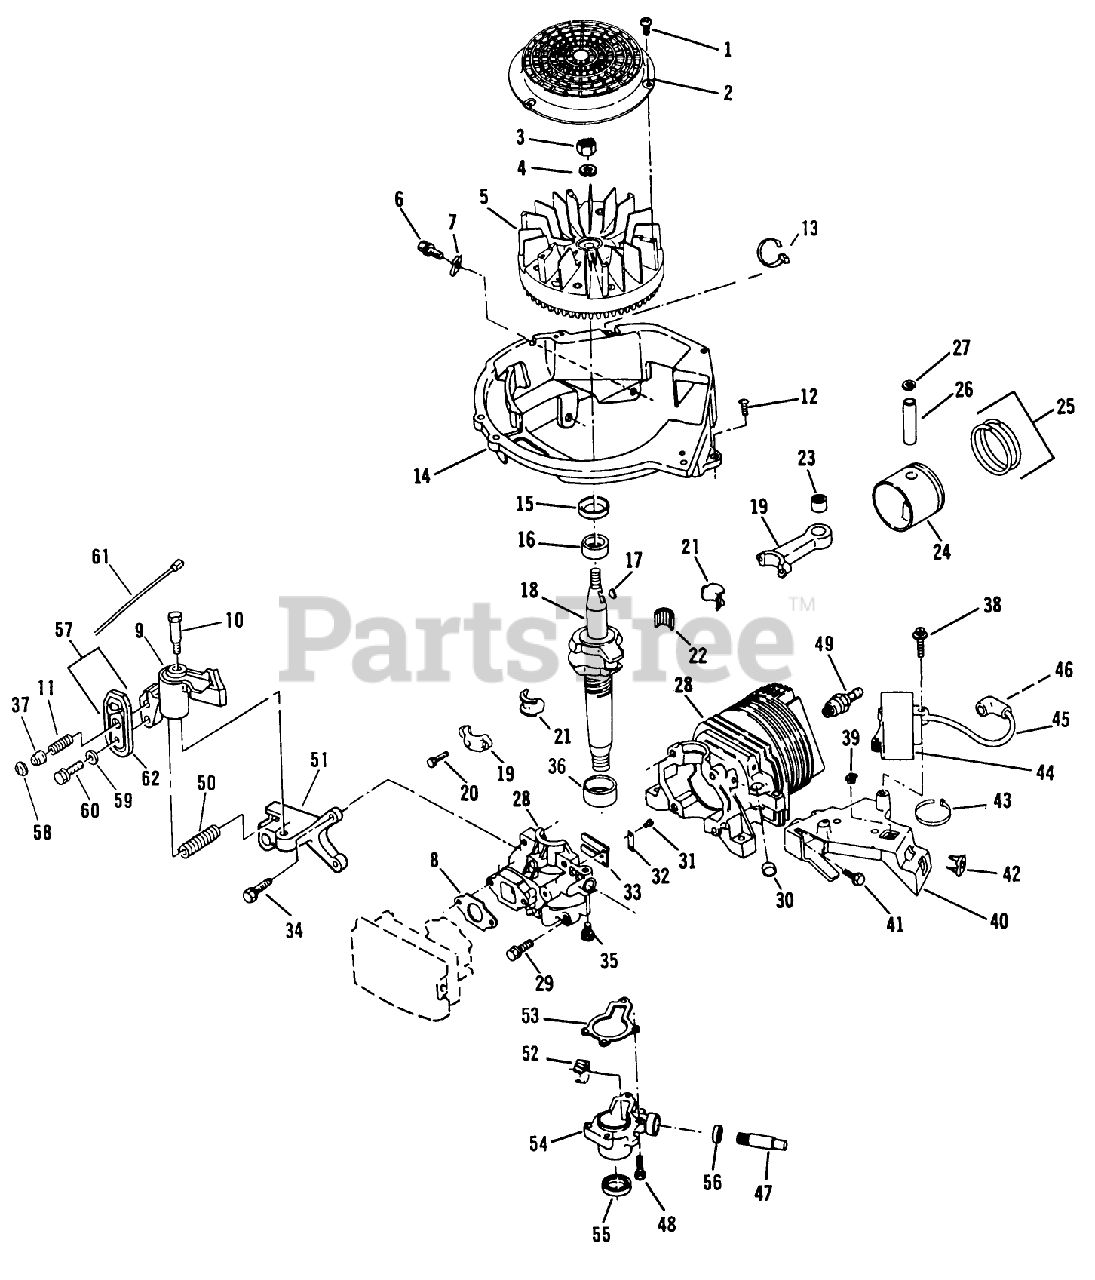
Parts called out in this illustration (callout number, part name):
1	SCREW F
3	NUT
5	FLYWHEEL ASSY F
6	SCREW-SEMS
8	GASKET CARB S
11	SPRING
12	SCREW F
15	SEAL-OIL
16	BEARING V
17	KEY
20	SCREW-HSH
21	LINER ASM
22	BEARING-NEEDLE
23	BEARING AY F
27	RING-RETAINING
29	SCREW-H.W.HD. F
30	PLUG-CORE VF
31	SCREW-HH
32	PLATE-BACKUP, REED
34	SCREW
36	BEARING S
37	ACTUATOR-LEVER, BRAKE
39	NUT-CLIP
42	NUT-CLIP
45	HT LEAD&COVER XEV
47	DR SHAFT,PTO S
50	SPRING-BRAKE
51	BRACKET-BRAKE F
53	GASKET S
55	SEAL-OIL
56	SEAL S
58	RETAINER S
59	WASHER
61	WIRE LEAD AY F
